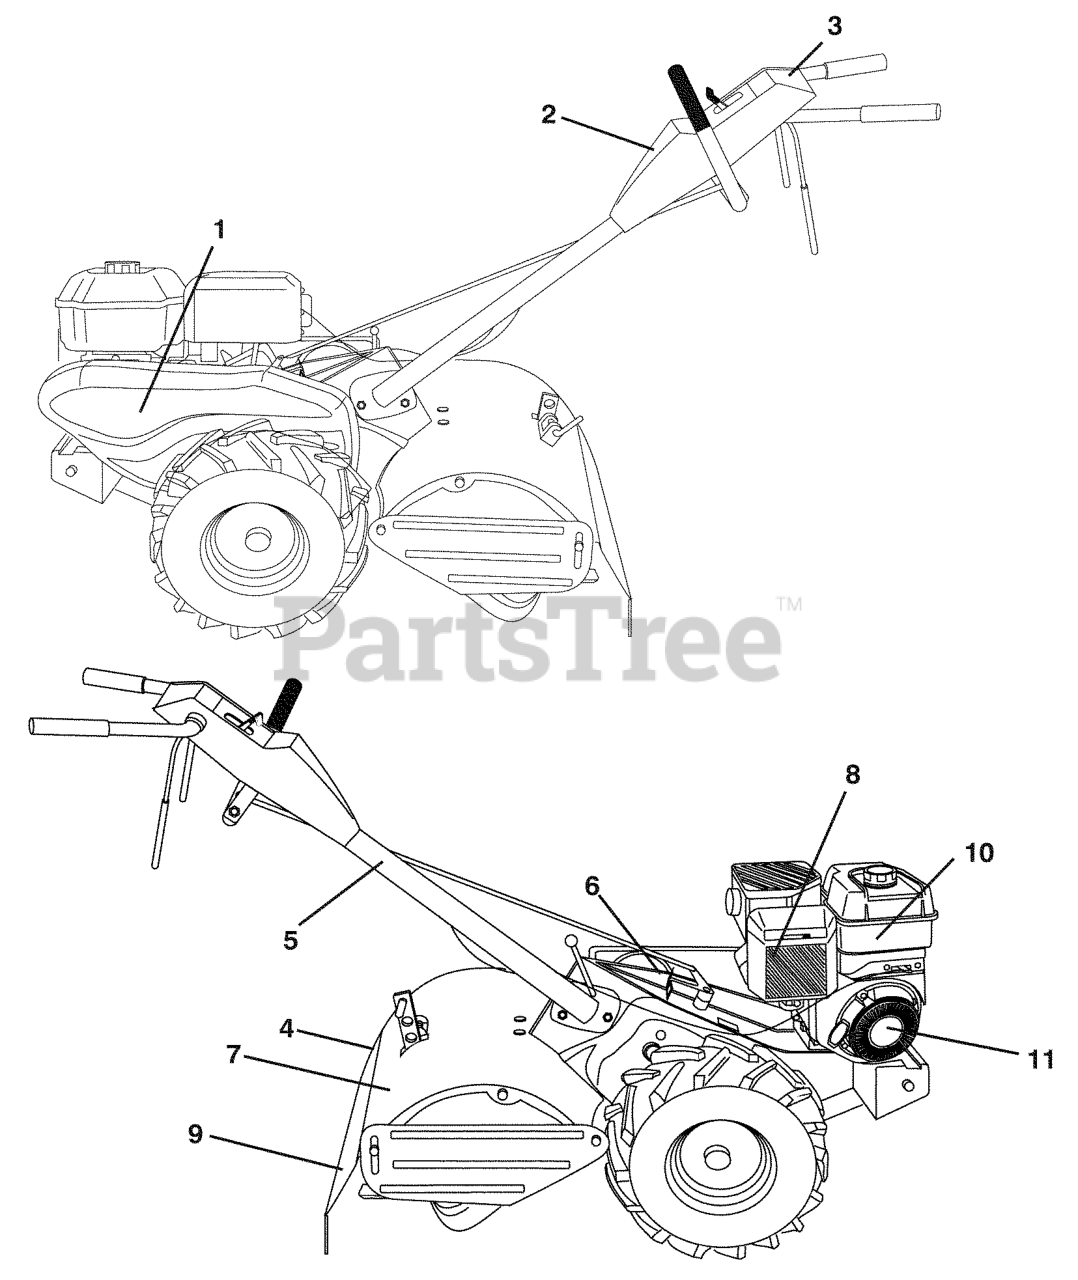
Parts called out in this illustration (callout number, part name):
1	DECAL.HOOD.LOGO.ORANGE.HUSQVAR
2	DECAL.CONSOLE.650RTT.HUSQ
3	DECAL CONTROL
4	DECAL.SHIELD.TN.CRT17.HUSQ.008
5	DECAL TI (2 2)
6	DECAL.SHIFT.INDICATOR.TILLER
7	DECAL.WARNING.SHLD.ENG/FR
8	DECAL.BS.850.A/C.REF.277442
9	DECAL TI
10	DECAL.BS.850.TANK.REF.276929
11	DECAL, REWIND STARTER, B&S
